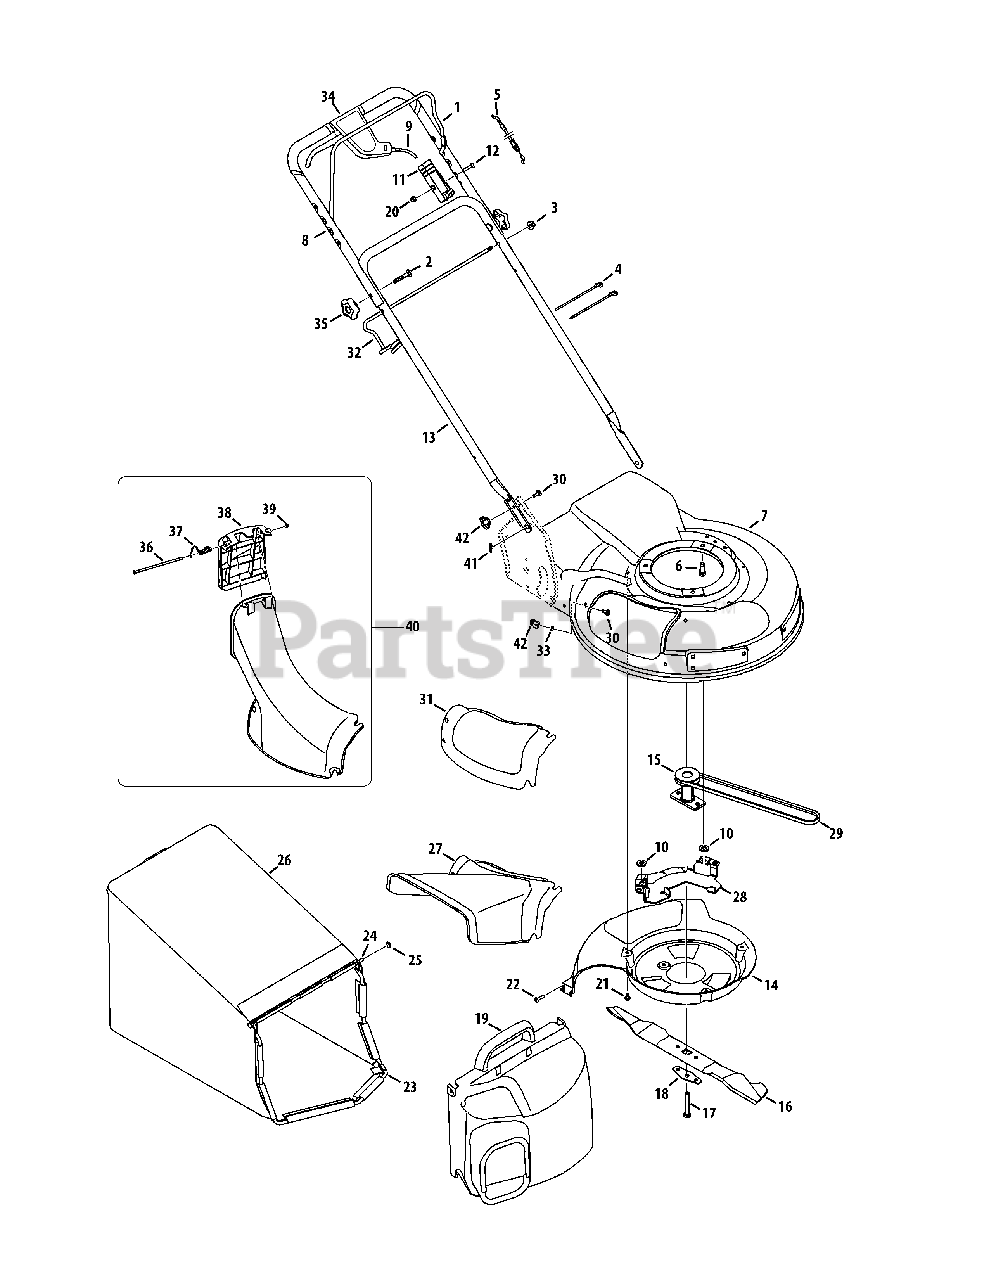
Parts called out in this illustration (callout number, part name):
1	Blade Control
2	Carriage Bolt 5/16-18 x 2
3	Flange Lock Nut, 5/16-18
4	Cable Tie
5	Control Cable
6	TT Screw, 3/8-16 x 1.00
7	21-inch Deck
8	Upper Handle
9	Drive Cable
10	Washer, Flat, .407 x .812 x .135
11	Control Cable Mount
12	Screw, 1/4-20 x 1.310
14	Rear Baffle
15	Blade Adapter
16	21-inch Mulching Blade
17	HH Cap Screw, 3/8-24 x 2.50
18	Bell Blade Spacer
19	Grass Bag Cover Assembly
20	Hex Lock Nut 1/4-20
21	TT Screw 1/4-20 x .375
22	HL Screw 1/4-15 x .75
23	Grass Bag Frame
24	Grass Bag Pivot Rod
25	Cap Speed Nut
26	Grass Bag Assembly
27	Side Discharge Chute
28	Belt Keeper
29	V-Belt
30	Carriage Screw 1/4-20 x .75
31	Mulch Cover
32	Grass Bag Support Rod
33	Push Nut
34	Drive Control Assembly
35	Star Knob
36	Chute Door Pivot Rod
37	Torsion Spring
38	Top Discharge Door Chute
39	Push Cap
40	Top Discharge Chute Assembly
41	Cotter Pin
42	Wing Nut
